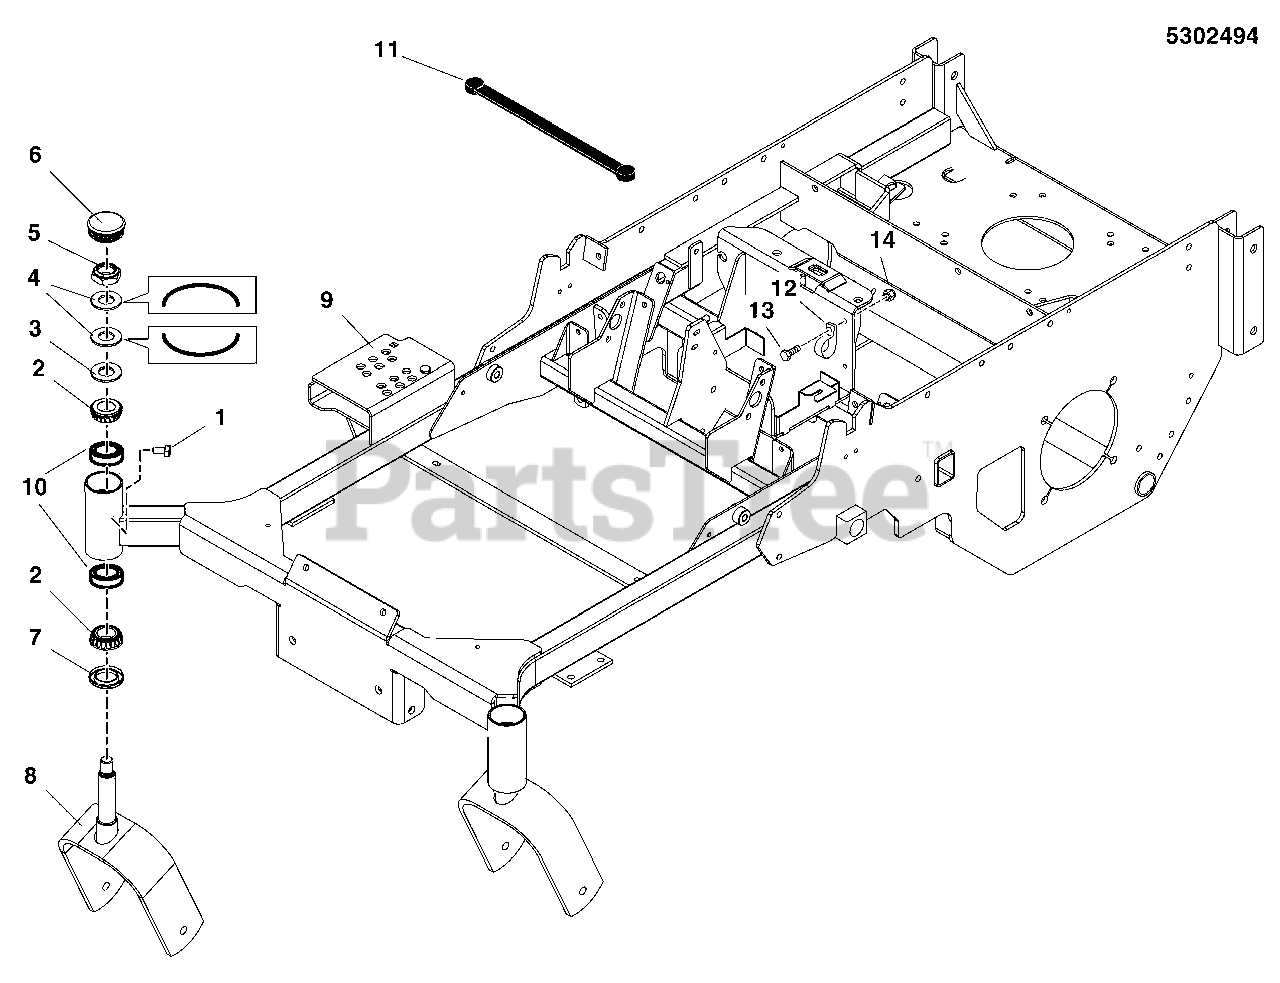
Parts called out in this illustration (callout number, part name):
1	BOLT, 1/4-28 X 1/2, GD5 YZ
2	BEARING, TAPERED ROLLER, 1
3	WASHER, 3/4 SAE
4	WASHER, BELLEVILLE - 1.500 X .755
5	NUT, 3/4-16, HEX JAM NYLON LOCK
6	CAP, GREASE, LOW PROFILE
7	SEAL, GREASE
8	WELD, CASTER YOKE - RED
9	WELD, MAIN FRAME, S150XT - RED
10	CUP, BEARING (SV)
11	STRAP-BLACK RUBB
12	CLAMP, VINYL INSULATED
13	BOLT, 1/4-20 X 3/4 GD5 YZ
14	NUT, 1/4-20 HEX SERR. FLANGE
